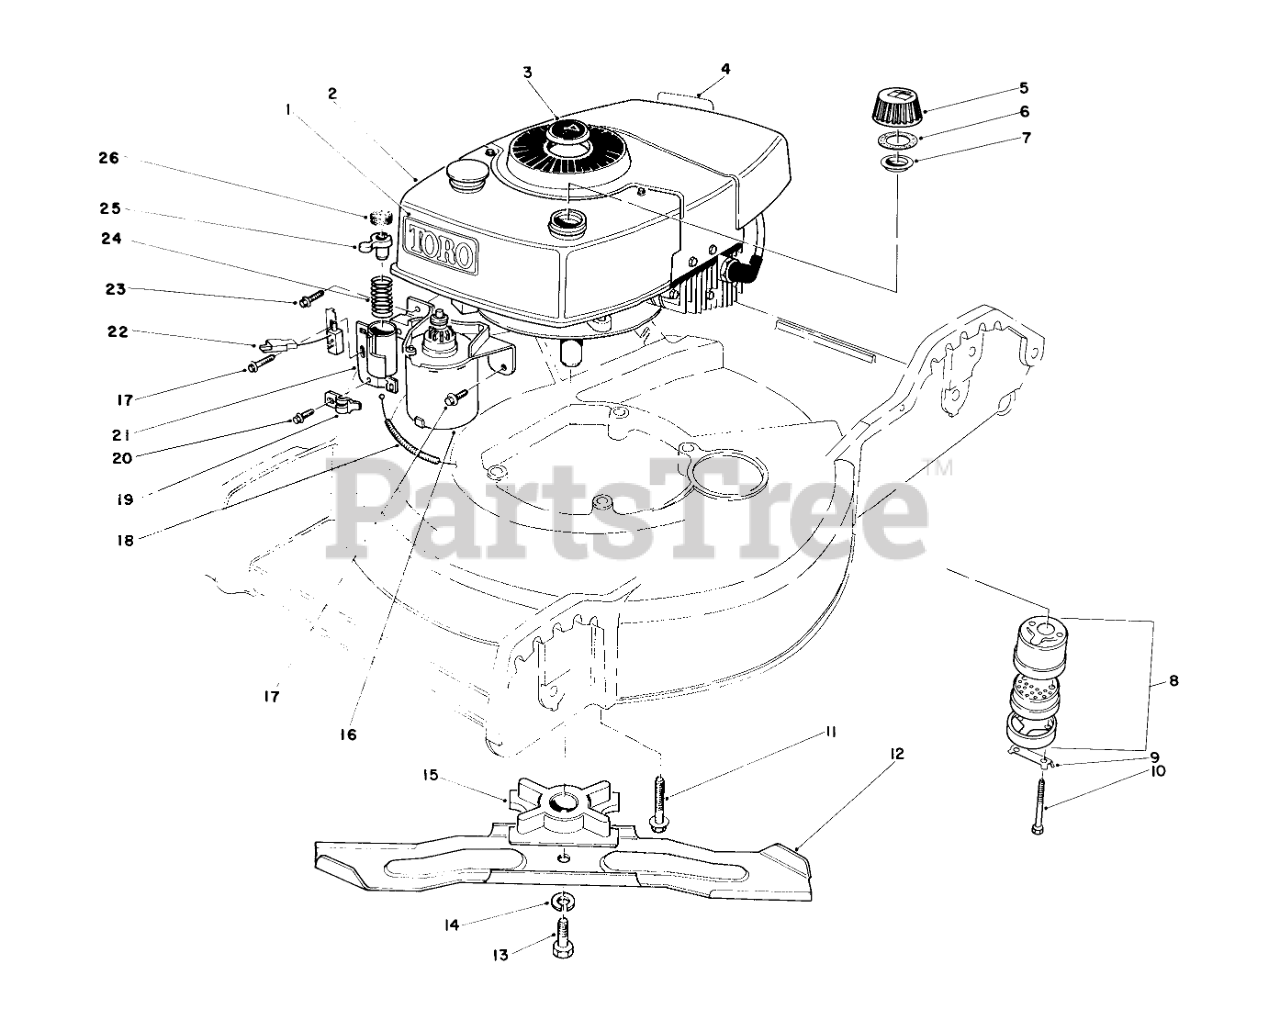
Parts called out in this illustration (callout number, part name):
1	Decal Tow
2	Engine
3	PLUG BUTTON
4	Decal-Maintenan
5	Gas Cap Assembly (Incl. Ref. #6 & 7)
6	GASKET
7	GAS CAP BAFFLE
8	Muffler Assembly (Incl. Ref. #9 & 10)
9	CLIP - LOCKING
10	SCREW-HH
11	3/8-16 X 2 CAPSCREW
12	Blade
13	SPECIAL SCREW
14	WASHER-LOCK
15	BLADE RETAINER
16	STARTER MOTOR ASM
17	SCREW
18	BRAKE CABLE-SUZUKI
19	CABLE CLAMP
20	SCREW
21	TUBE W A
22	PUSH BUTTON SWITCH
23	Screw
24	COMPRESSION SPRING
25	Plunger
26	Pad-Friction
